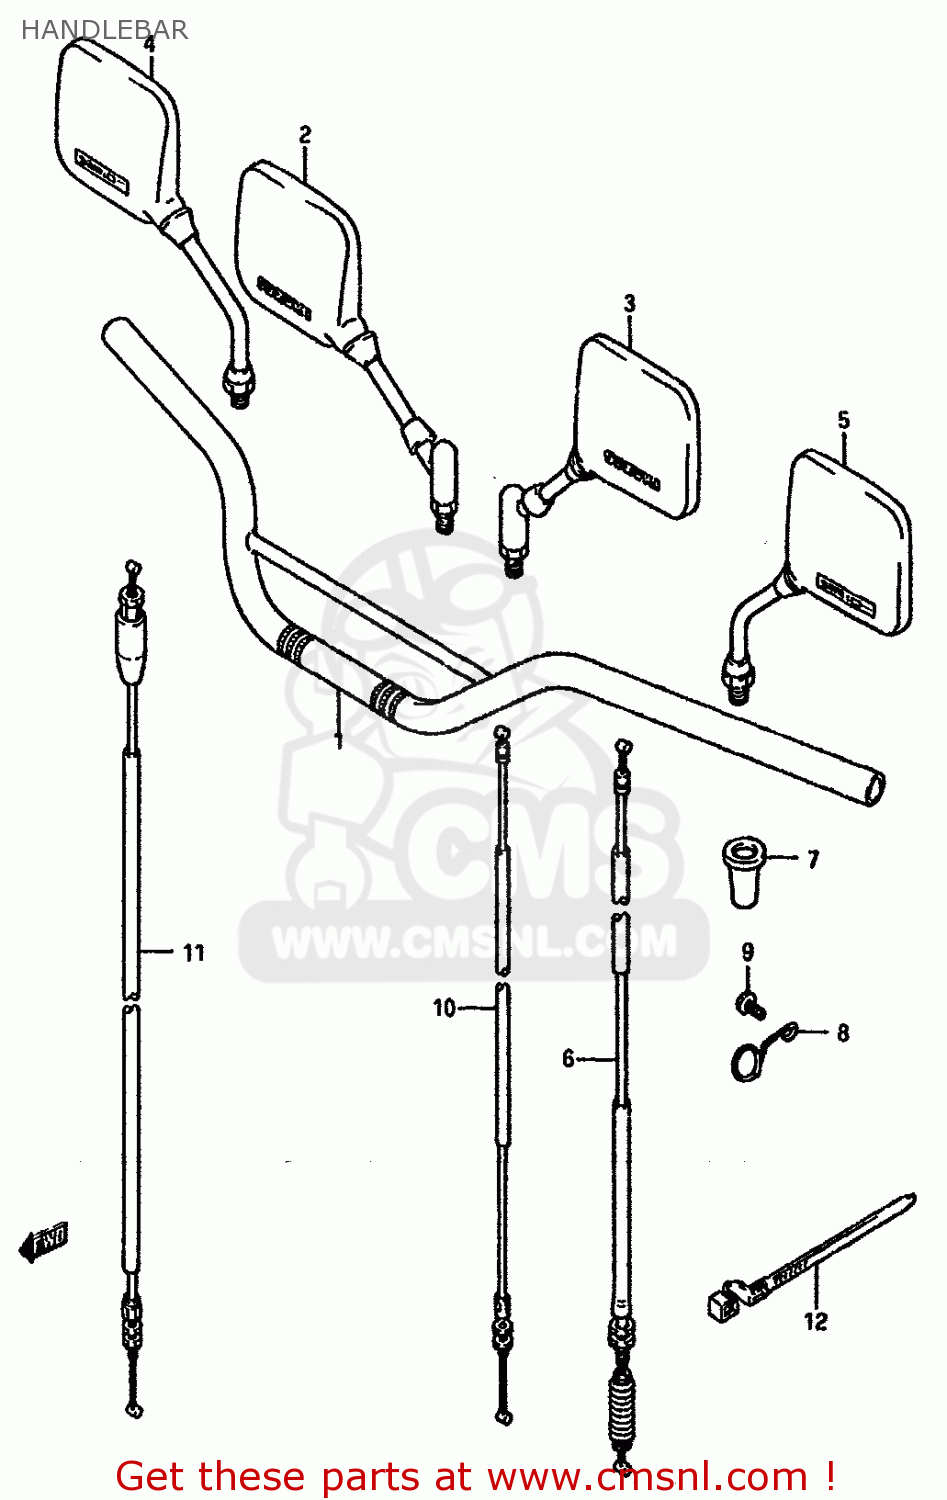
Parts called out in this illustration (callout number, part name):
1	HANDLEBAR(BLACK)
2	MIRROR ASSEMBLY,REAR VIEW
3	MIRROR ASSEMBLY,REAR VIEW
4	MIRROR, REAR VIEW RH
5	MIRROR ASSEMBLY,LEFT
6	CABLE ASSY,CLU
7	BOOT,CLUTCH CABLE
8	CLIP
9	SCREW
10	CABLE ASSY,DECOMPPRESION
11	CABLE ASSY,THROTTLE
12	CLAMP, CABLE
